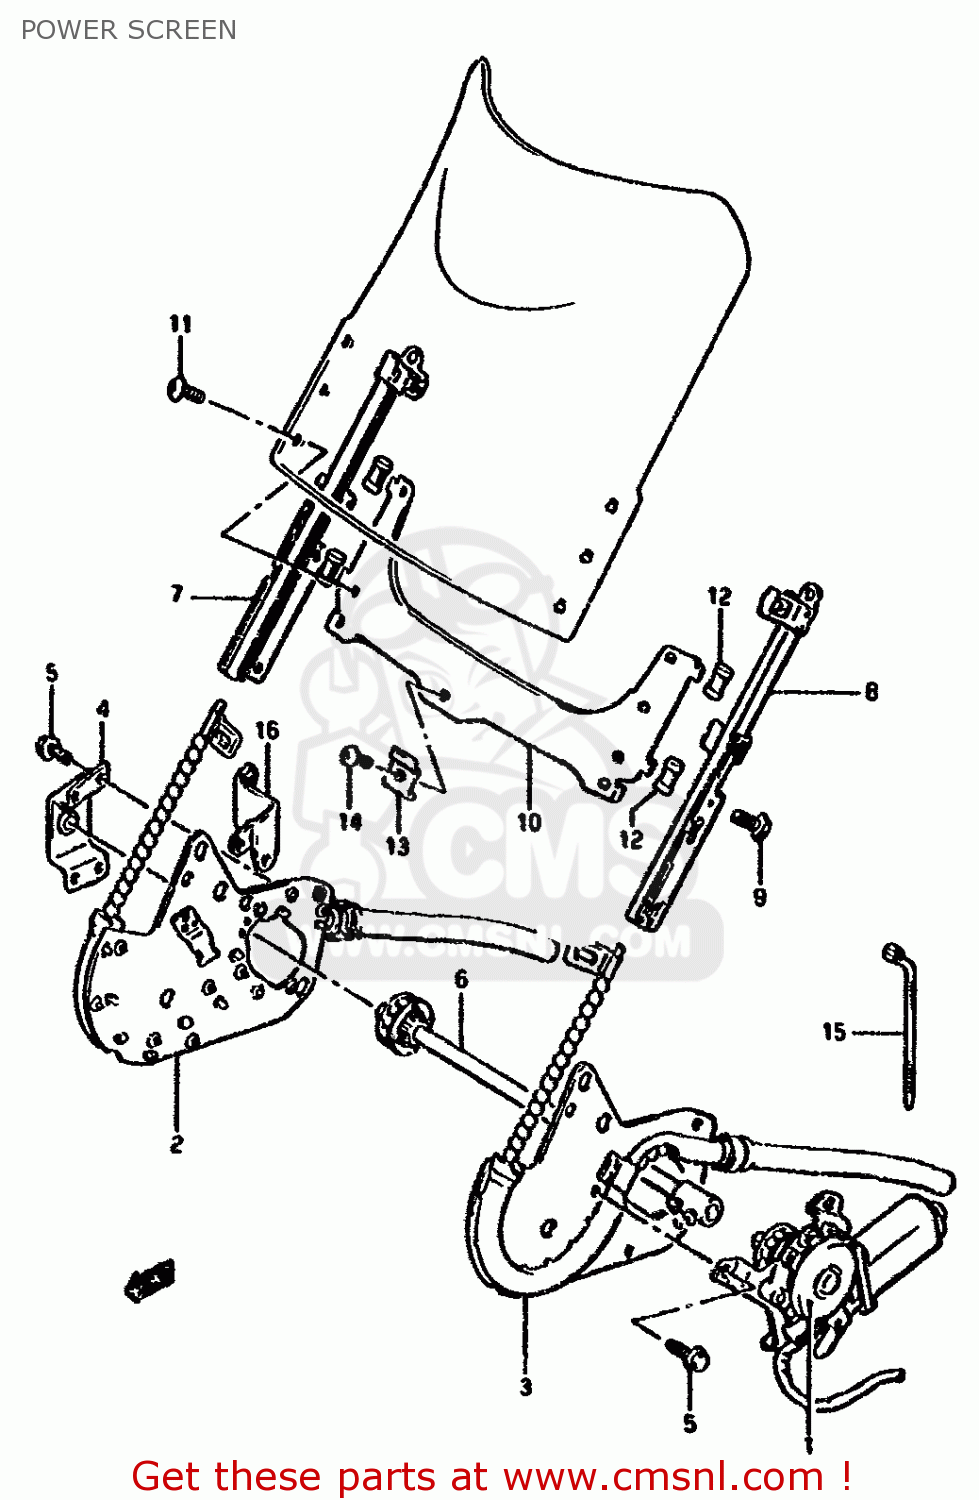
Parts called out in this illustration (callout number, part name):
1	MOTOR SET
2	FRAME SET,RIGHT
3	FRAME SET,L
4	METAL BRACKET SET
5	BOLT
6	SHAFT SET
7	PIPE SET,GUIDE,R
8	PIPE SET,GUIDE,L
9	BOLT
10	BRACKET,SCREEN
11	SCREW, FRONT & REAR
12	RUBBER,SLIDE
13	BRACKET,SUPPORT
14	SCREW
15	CLAMP
16	BRACKET
